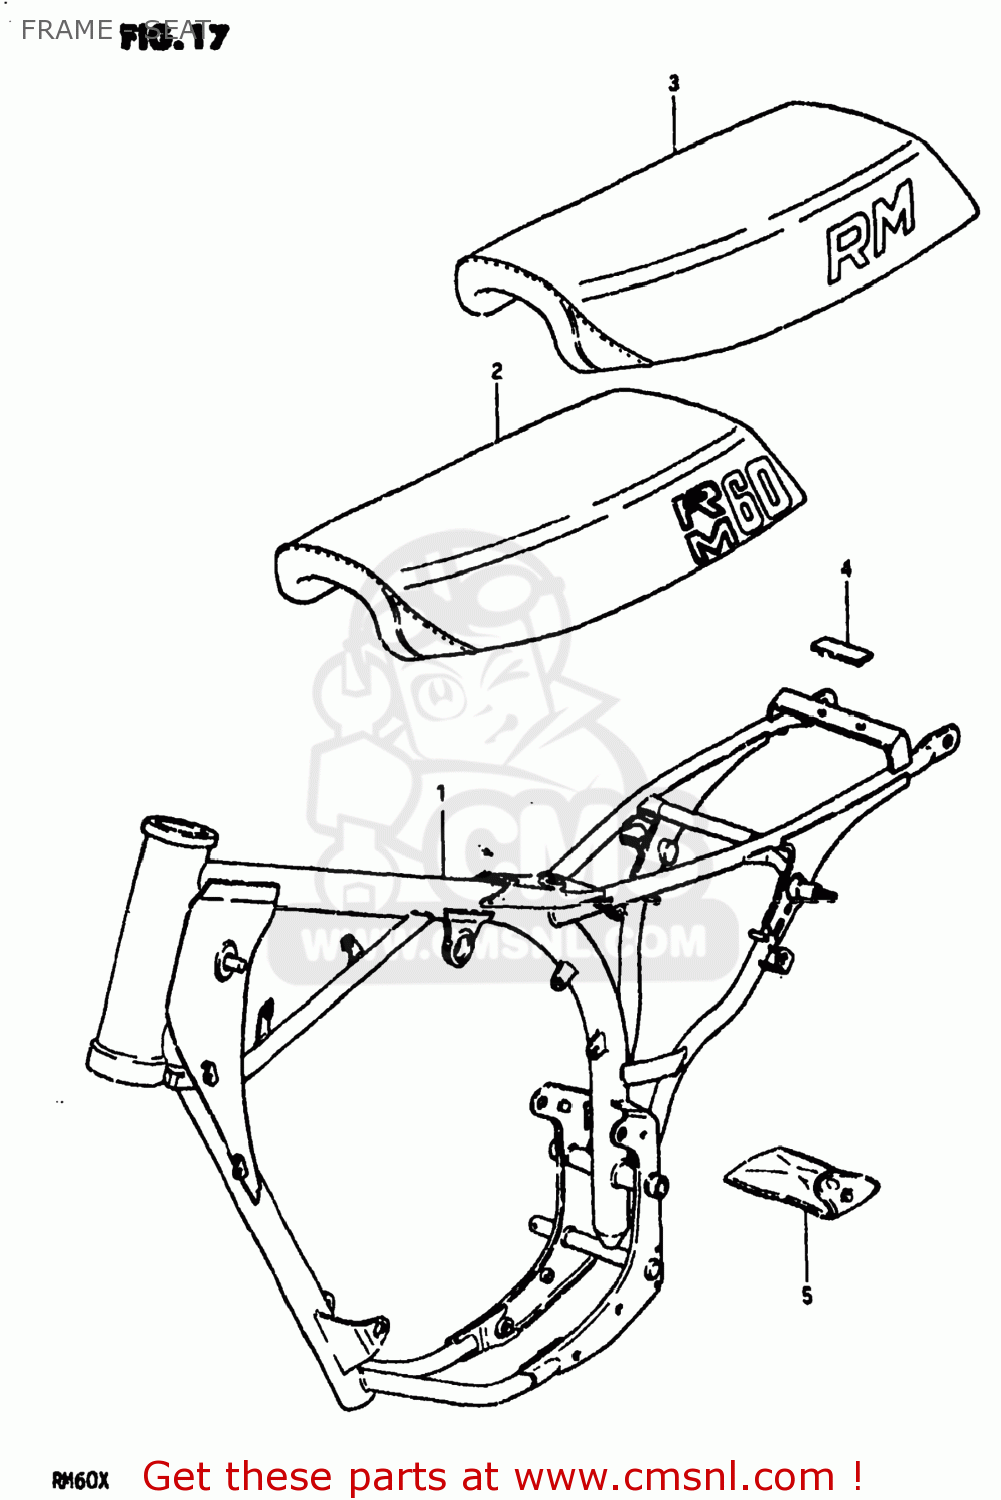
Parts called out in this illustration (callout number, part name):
1	FRAME
2	SEAT ASSEMBLY
3	SEAT ASSEMBLY
4	CUSHION
5	TOOL SET
